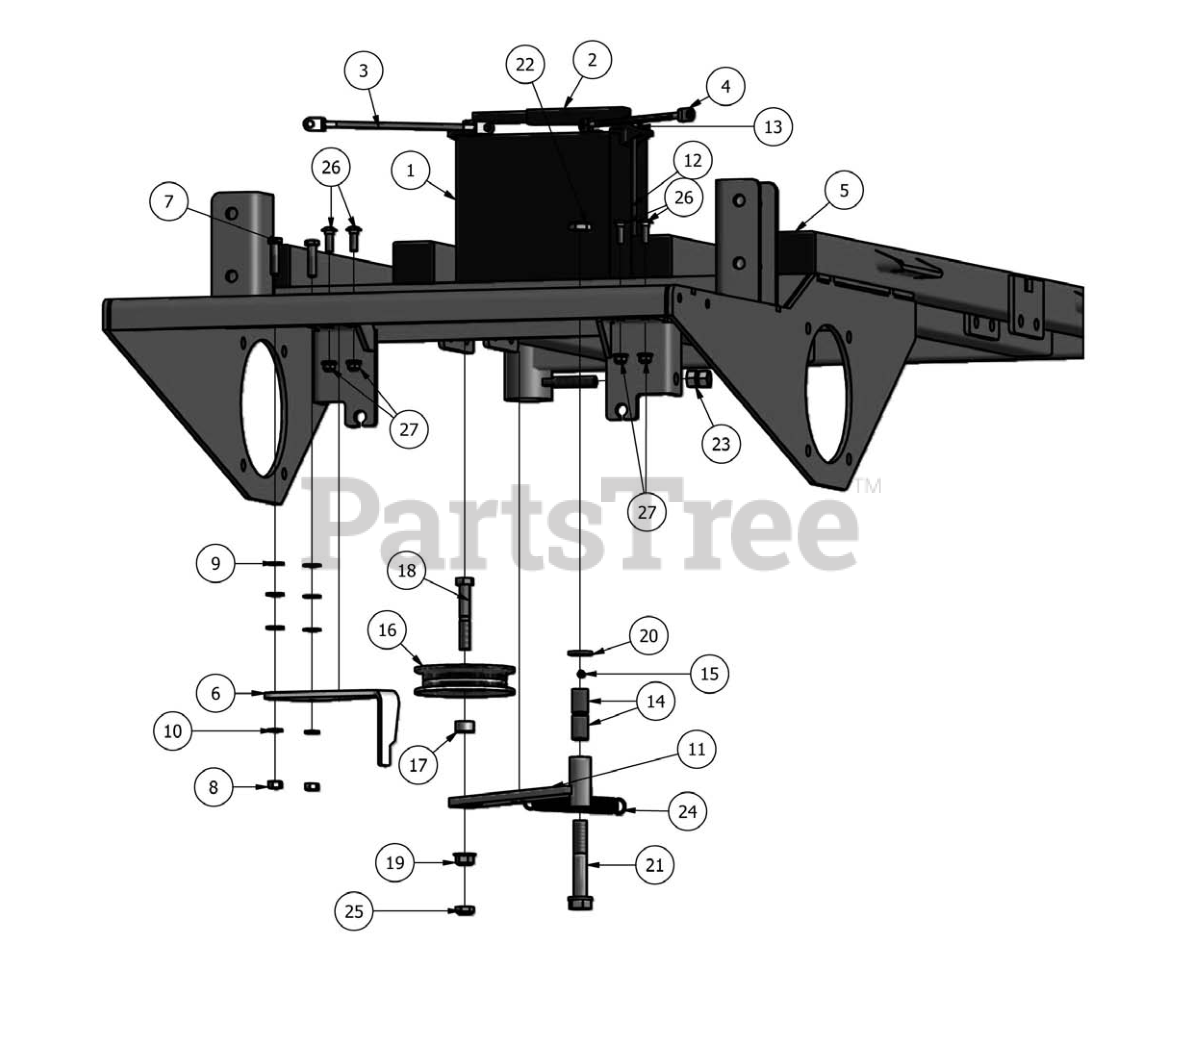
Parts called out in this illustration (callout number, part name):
1	Workaholic
2	Battery Hold Down
3	24" Red Cable
4	Ground Cable
5	2x2 Square Plug
6	PTO Engager Holder
7	3/8-16 x 1-1/2 GR5 Hex Bolt
8	3/8-16 Hex Nuts Zinc
9	3/8 USS Flat Washer Zinc
10	3/8 Lockwasher Zinc
11	Pump Idler Bracket
12	1/4-20 x 8 Carriage Bolt Zinc
13	1/4-20 Wing Nut Zinc
14	Brass Bushing- 5/8 x 1 1/8- SS-2024-18
15	1/4" Drive in Grease Fitting
16	4 3/4" Idler Pulley
17	1/2" Set collar
18	1/2 x 3 Grade 5 Hex Bolt
19	1/2-13 Nylon Insert Flange Nut Zinc Orange Nylon
20	.630 ID X 1.122 OD X.142 THK Flat Washer Nylon
21	5/8-11 X 4 GR 5 Hex Bolts Zinc
22	5/8-11 Nylon Insert Jam Locknut Zinc
23	1/2-13 Hex Nuts Zinc
24	Pump Idler Spring
25	1/2-20 Nylon Insert Jam Locknut Zinc Orange Zinc
26	5/16-18 x 1 Carriage Bolts Zinc
27	5/16" Nylock Flange Nut
